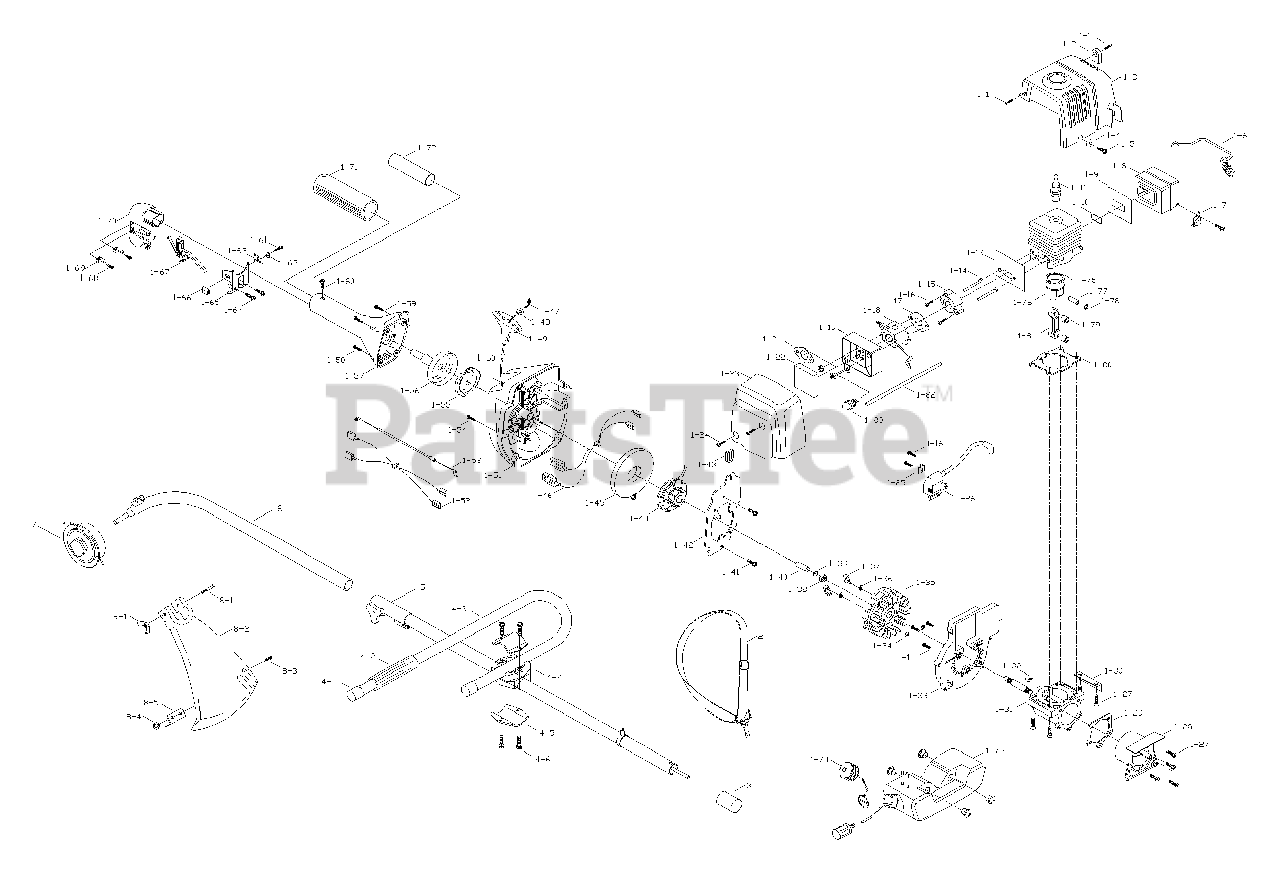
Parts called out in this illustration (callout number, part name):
1	ENG ASS'Y
1-1	SCREW
1-2	WASHER, PLASTIC
1-5	SCREW
1-6	SPRING, MUFFLER
1-7	SCREEN, SPARK ARRESTER
1-8	KIT, MUFFLER
1-9	GASKET, MUFFLER
1-10	GASKET
1-11	SPARK PLUG
1-12	KIT, CYLINDER/GASKET
1-13	GASKET, MUFFLER
1-14	SCREW
1-15	MANIFOLD, CARBURETOR
1-16	SCREW
1-17	GASKET, CARBURETOR
1-18	CARBURETOR ASS'Y
1-19	BOX, AIR
1-21	GASKET
1-22	FILTER, AIR
1-23	COVER, AIR CLEANER
1-25	TERMINAL TAB
1-26	IGNITION ASSENBLY
1-27	SCREW
1-28	PLUG, C'CASE
1-29	GASKET
1-30	SHIELD, MUFFLER
1-31	C'CASE/C'SHAFT ASS'Y
1-32	KEY,FLYWHEEL
1-33	SHIELD MUFFLER
1-34	RING, RETAINER
1-35	FLYWHEEL
1-37	PAWL KIT, STARTER
1-41	SCREW
1-42	RETAINER, PULLEY
1-43	GROMMET
1-44	DRUM/ ROPE ASS'Y
1-45	PACKAGE, SPRING ASS'Y
1-46	WIRE ASS'Y
1-47	ROPE, STARTER
1-48	WASHER, NYLON
1-49	HANDLE, STARTER
1-50	GUIDE, ROPE
1-52	WIRE ASS'Y, SWITCH
1-53	THROTTLE CABLE ASS'Y
1-55	KIT ASS'Y, CLUTCH
1-56	DRUM ASS'Y, CLUTCH
1-57	HOUSING, CLUTCH
1-58	SCREW
1-59	SCREW
1-60	SCREW
1-61	SCREW
1-63	CONTACT, SWITCH
1-65	COVER ASS'Y, SWITCH
1-66	BUTTON, STOP SWITCH
1-67	TRIGGER, THROTTLE
1-69	TERMINAL TAB
1-70	TRIGGER HOUSING
1-72	SLEEVE, PROTECTING
1-73	TANK ASS'Y
1-74	CAP, FUEL TANK
1-75	RING, PISTON
1-80	GASKET,CYLINDER
2	HARNESS
4	HANDLE ASS'Y
4-3	J-HANDLE
4-4	CENTERPIECE
4-5	CLAMP
4-6	SCREW
5	REAR SHAFT ASS'Y
6	FRONT SHAFT ASS'Y
7	STRINGHEAD ASS'Y
8	GRASS SHIELD ASS'Y
8-1	SCREW/NUT ASS'Y
8-2	SHIELD
8-3	SCREW
8-4	NUT
